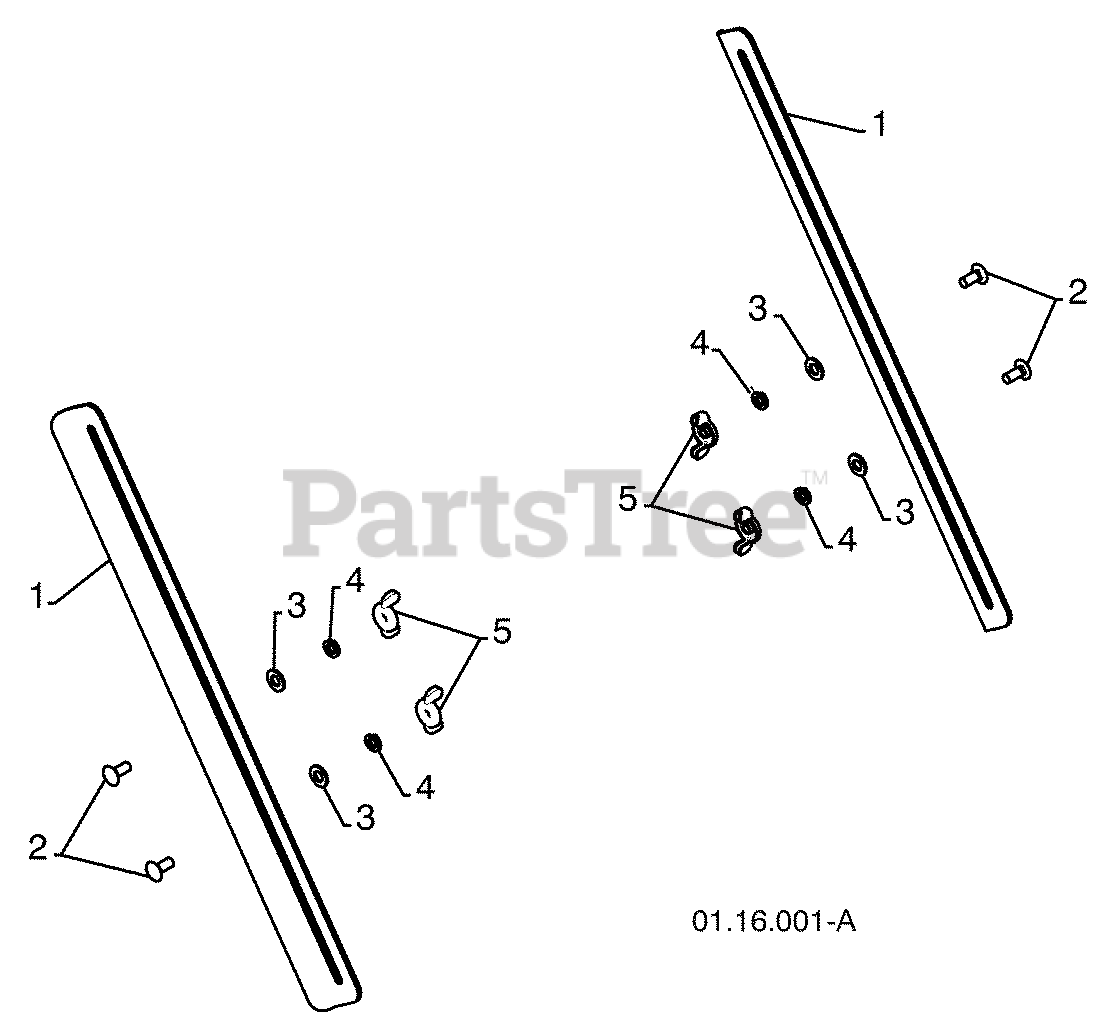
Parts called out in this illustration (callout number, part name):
1	DRIFT CUTTER BAR
2	CARRIAGE BOLT 5/16-18 X .750
3	PLASTIC WASHER
4	LOCKWASHER 5/16
5	NUT 5/16-18
